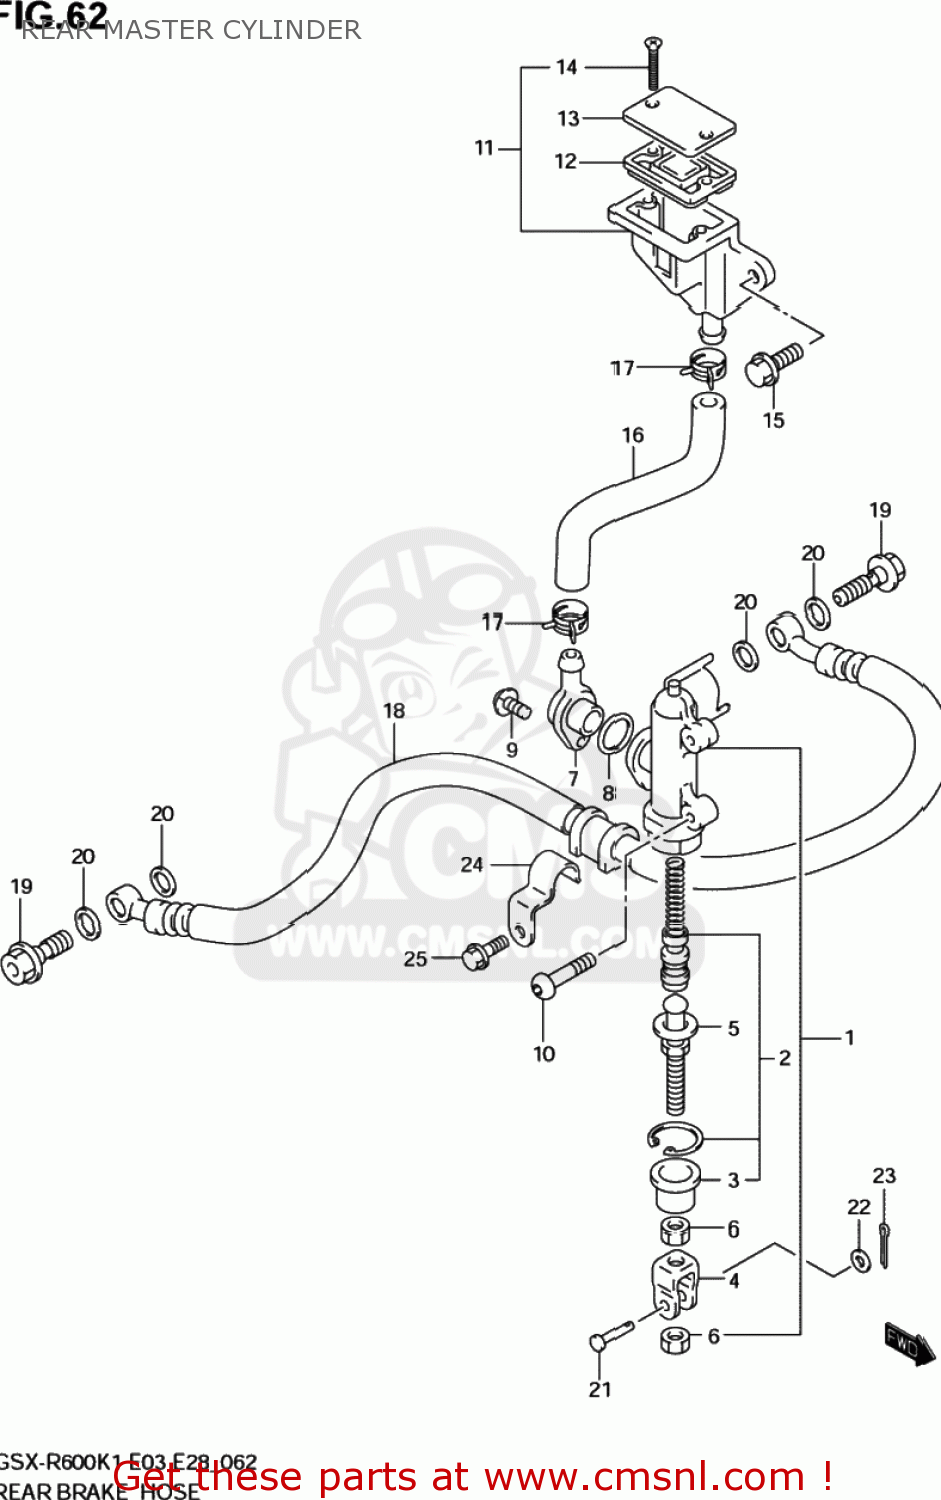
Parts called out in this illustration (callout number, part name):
1	CYLINDER ASSY,RR MASTER
2	PISTON/CUP SET
3	BOOT
4	YOKE
5	ROD,PUSH
6	NUT
7	CONNECTOR
8	O RING
9	SCREW
10	SCREW(6X20)
11	TANK ASSY,RR RESERVOIR
12	DIAPHRAGM
13	CAP
14	SCREW
15	BOLT(6X12)
16	HOSE,RESERVOIR TANK
17	CLIP
18	HOSE,RR BRAKE
19	BOLT UNION
20	WASHER(10X15X1.5)
21	PIN
22	WASHER
23	PIN
24	CLAMP,RR BRAKE HOSE
25	BOLT
